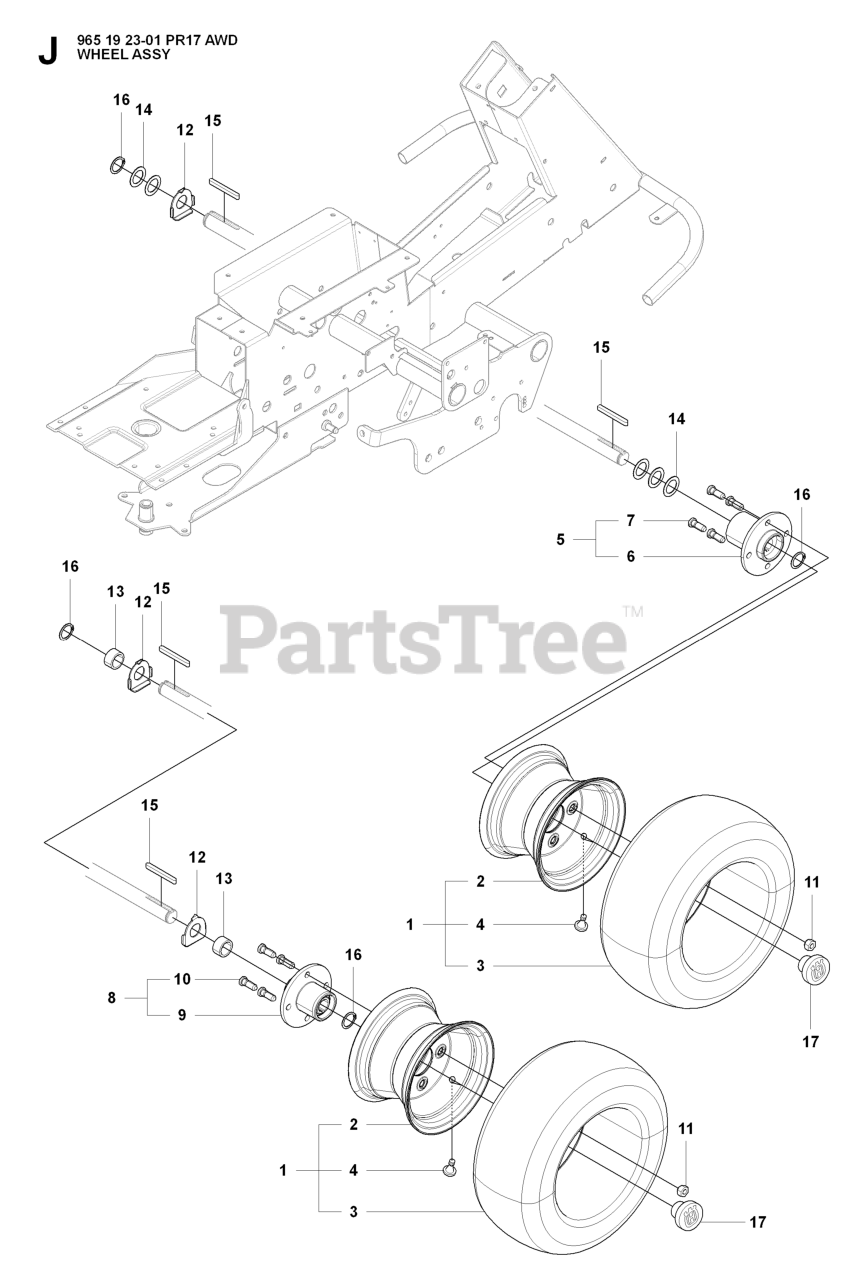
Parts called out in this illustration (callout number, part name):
4	VALVE
12	WASHER STEEL
16	RETAINING RING SGA 25
